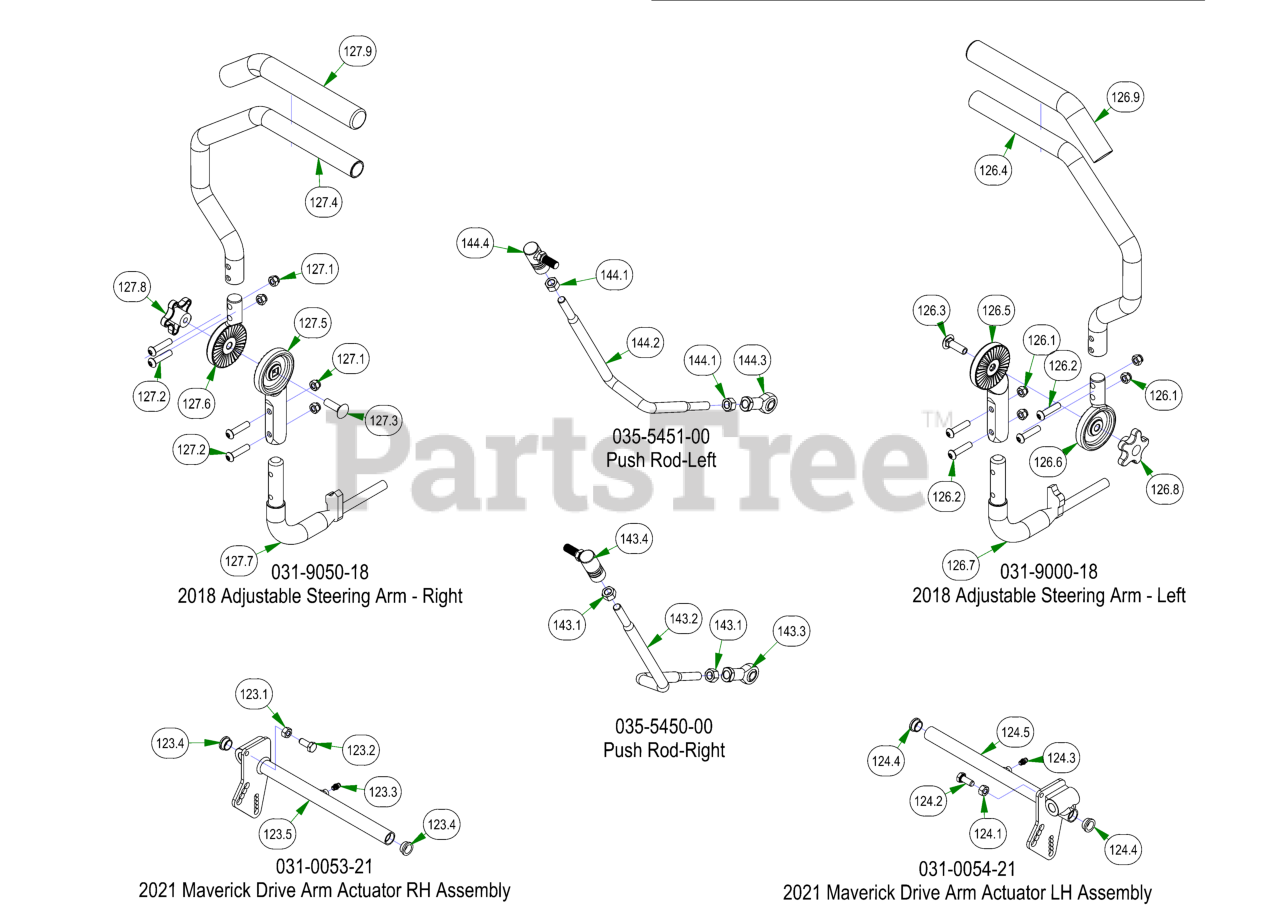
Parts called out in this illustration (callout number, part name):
59	5/16-18 X 1-1/4 CARRIAGE BOLT ZINC
108	2023 4" & 5" Stripping Kit Plate
123	2021 Maverick Drive Arm Actuator RH Assembly
123.1	5/16-18 HEX NUT ZINC
123.2	5/16-18 X 3/4 HEX CAP SCREW (GR.5) ZINC
123.3	1/4" Press in Grease Fitting
123.4	2019 Drive Arm Bushing
123.5	2021 Drive Actuator RH Weldment
124	2021 Maverick Drive Arm Actuator LH Assembly
124.1	5/16-18 HEX NUT ZINC
124.2	5/16-18 X 3/4 HEX CAP SCREW (GR.5) ZINC
124.3	1/4" Press in Grease Fitting
124.4	2019 Drive Arm Bushing
124.5	2021 Drive Actuator LH Weldment
126	2018 Adjustable Steering Arm - Left
126.1	5/16-18 NYL INS L/N ZC
126.2	5/16-18 UNC X 1-3/8" BHCS, TORX DRIVE, GR 5
126.3	3/8-16 X 1-1/4 CARRIAGE BOLT ZINC
126.4	Upper Tube-Adjustable Steering
126.5	2018 Lower Adjuster - Steering Arm- Left
126.6	2018 Upper Adjuster - Steering Arm- Left
126.7	Steering Arm Elbow (Left)
126.8	Black Knob for Adjustable Steering Arm
126.9	Rubber Grip
127	2018 Adjustable Steering Arm - Right
127.1	5/16-18 NYL INS L/N ZC
127.2	5/16-18 UNC X 1-3/8" BHCS, TORX DRIVE, GR 5
127.3	3/8-16 X 1-1/4 CARRIAGE BOLT ZINC
127.4	Upper Tube-Adjustable Steering
127.5	2018 Lower Adjuster - Steering Arm- Right
127.6	2018 Upper Adjuster - Steering Arm- Right
127.7	Steering Arm Elbow (Right)
127.8	Black Knob for Adjustable Steering Arm
127.9	Rubber Grip
143	Push Rod-Right
143.1	3/8" Fine Threaded Jam Nut
143.2	Push Rod - Right (Rod Only)
143.3	Spherical Rod End - Outlaw
143.4	Quick Release Ball Joint
144	Push Rod-Left
144.1	3/8" Fine Threaded Jam Nut
144.2	Push Rod LH (Rod Only)
144.3	Spherical Rod End - Outlaw
144.4	Quick Release Ball Joint
202	2023 ZT Stripping Kit Rubber
